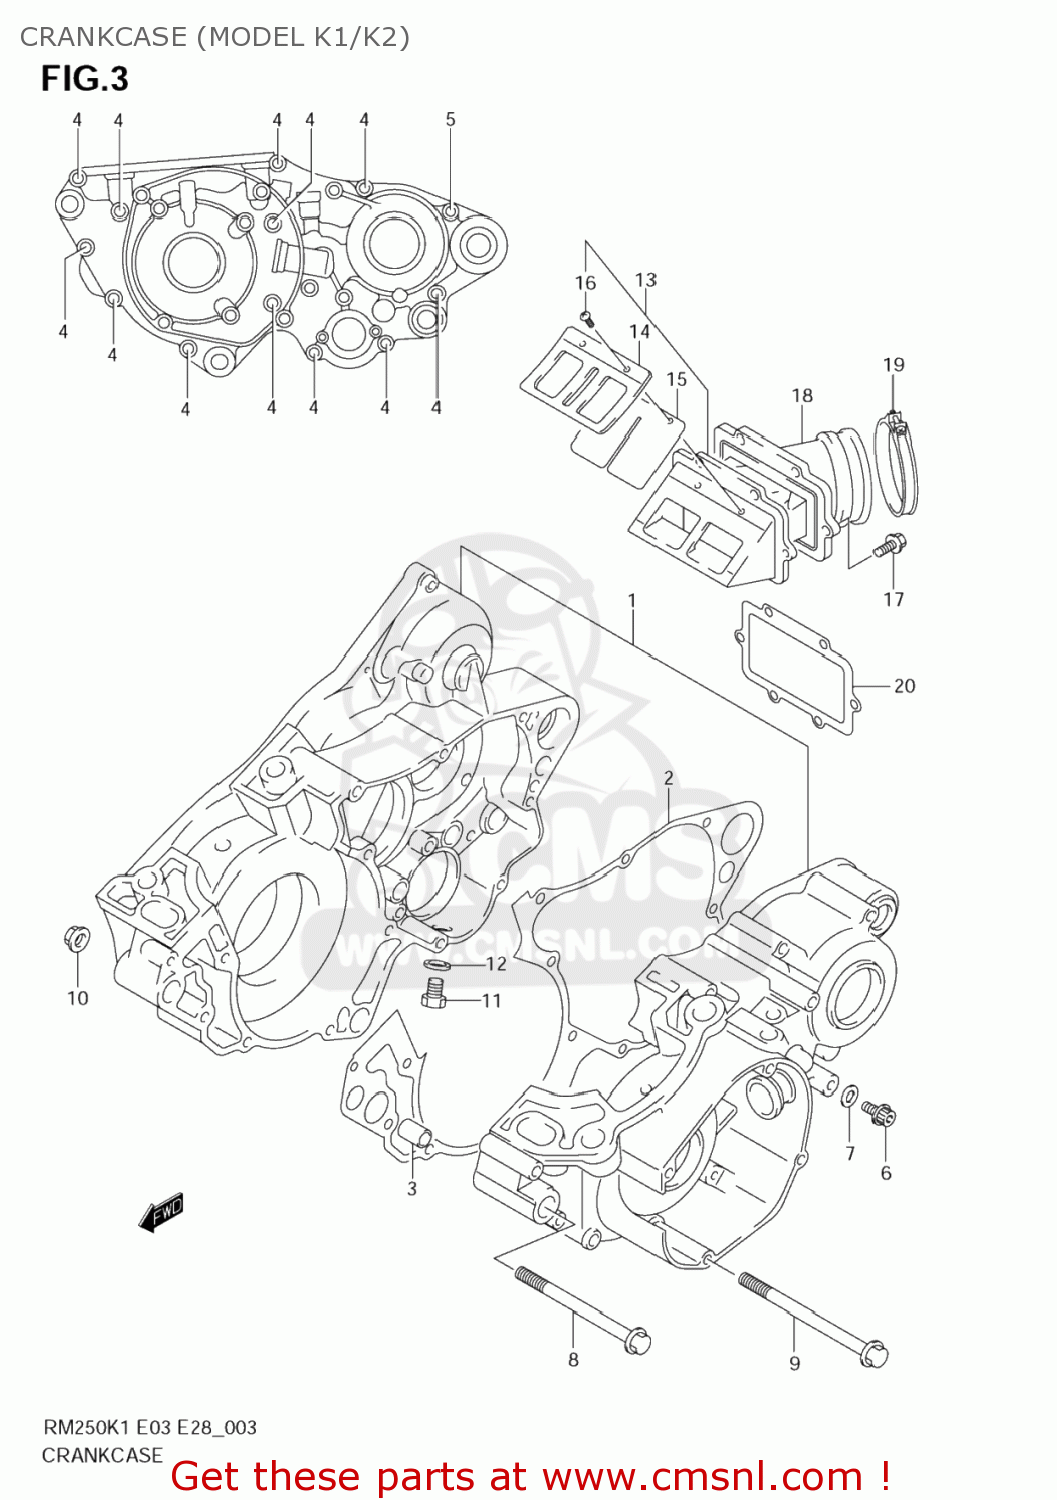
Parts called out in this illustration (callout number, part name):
1	CRANKCASE SET
2	GASKET,CRANKCA (NAS)
3	PIN(13X10.4X20)
4	BOLT(6X50)
5	BOLT(6X65)
6	BOLT
7	GASKET(6.2X11X1).2 (NAS)
8	BOLT(10X105)
9	BOLT(10X118)
10	NUT
11	Bolt
12	GASKET(12.1X16.2X3.7) (NAS)
13	VALVE ASSY,REED
14	STOPPER,REED VALVE
15	VALVE,REED
16	SCREW
17	SCREW
18	PIPE,INTAKE
19	CLAMP
20	GASKET,REED VALVE
